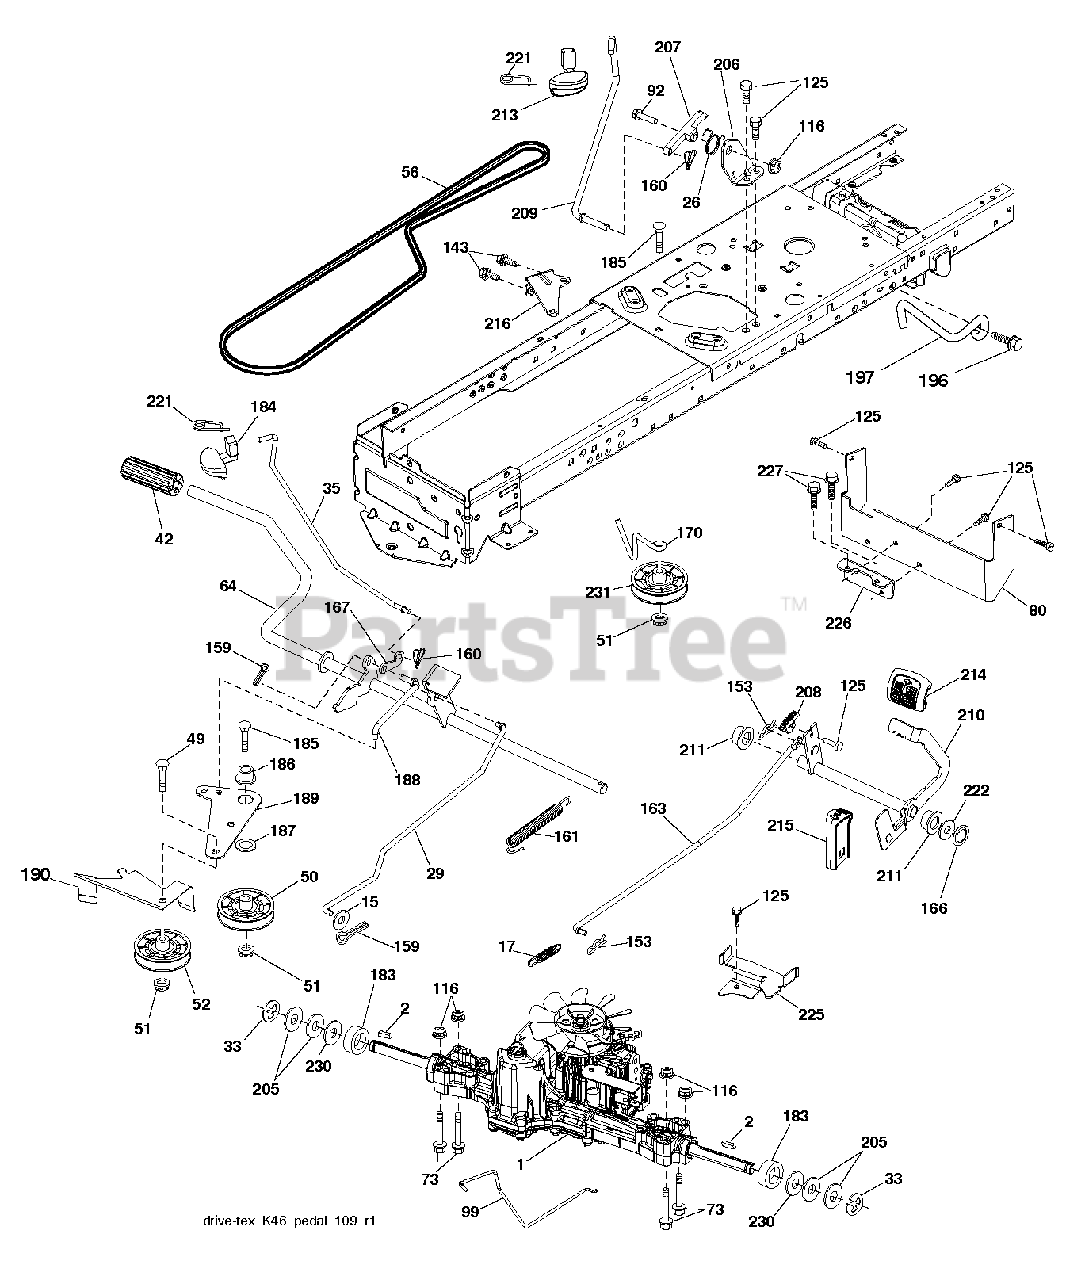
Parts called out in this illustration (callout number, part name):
2	SQUARE KEY
15	WASHER
17	SPRING.BRAKE.K46.GREEN
26	SPRING.RETURN.CRUISE
29	ROD.BRAKE.K46
33	E-RING LT
35	ROD.BRAKE.PARKING.STEALTH
50	IDLER.FLAT.910.OFFSET
51	NUT LOCK FLG 3/8-16 UNC
52	IDLER.V-GROOVE.910.OFFSET
56	V-BELT.MOWER.92.40.42/K46
64	SHAFT.ASM.PEDAL.BRK.CNTR
80	STRAP.TORQUE.K46.K57R.TT
92	BOLT
99	ROD.SPRING.BYPASS.K46.LT.Z
116	NUT LOCK HEX FLANGE 5/16-18
125	SCREW
143	SCREW LT
159	COTTER PIN
160	RETAINER CLIP
161	SPRING, RETURN LT
163	ROD.CONTROL.K57R.K46
166	NUT.PUSH.625
167	LATCH.BRAKE.SPRING
170	KEEPER.CENTER SPAN.1.688
183	SPACER AXLE
184	HANDLE.PRKG.BRAKE.STLTH.TX.RED
186	SPACER.RETAINER
187	WASHER 12/32X2X10GA
188	LINK.CLUTCH.GROUND.DRIVE
189	BELLCRANK.GROUND.DRIVE.TEX.
190	KEEPER.BELLCRANK.DRIVE
196	SCREW 3/8-16X1
197	LINK.CLUTCH.ANIT-ROTAT
206	BRACKET.MOUNT.CRUISE.LATCH
207	LATCH.CONTROL.CRUISE
208	GEAR.SECTOR.CONTROL.CR
209	ROD.CONTROL.CRUISE.STEALTH.TEX
210	ROCKER.ASM.PEDAL.CONTR
211	BEARING.NYLON
213	KNOB.CONTROL.CRUISE
214	PEDAL.FORWARD.PAD.TEX
215	PEDAL.REVERSE.TEX.GT.4
216	BRACKET.PULLEY.IDLER.W/TEX
221	RETAINER.SPRING.CLIP.H
222	WASHER 21/32 X 1-1/4 X 10 GA.
225	KEEPER.BELT.TRANSAXLE.K46
226	BRACKET.MOUNT.TORQUE.K46.TLT
230	WASHER.HARDENED
231	IDLER.V-GROOVE.1.688.OFFSET
